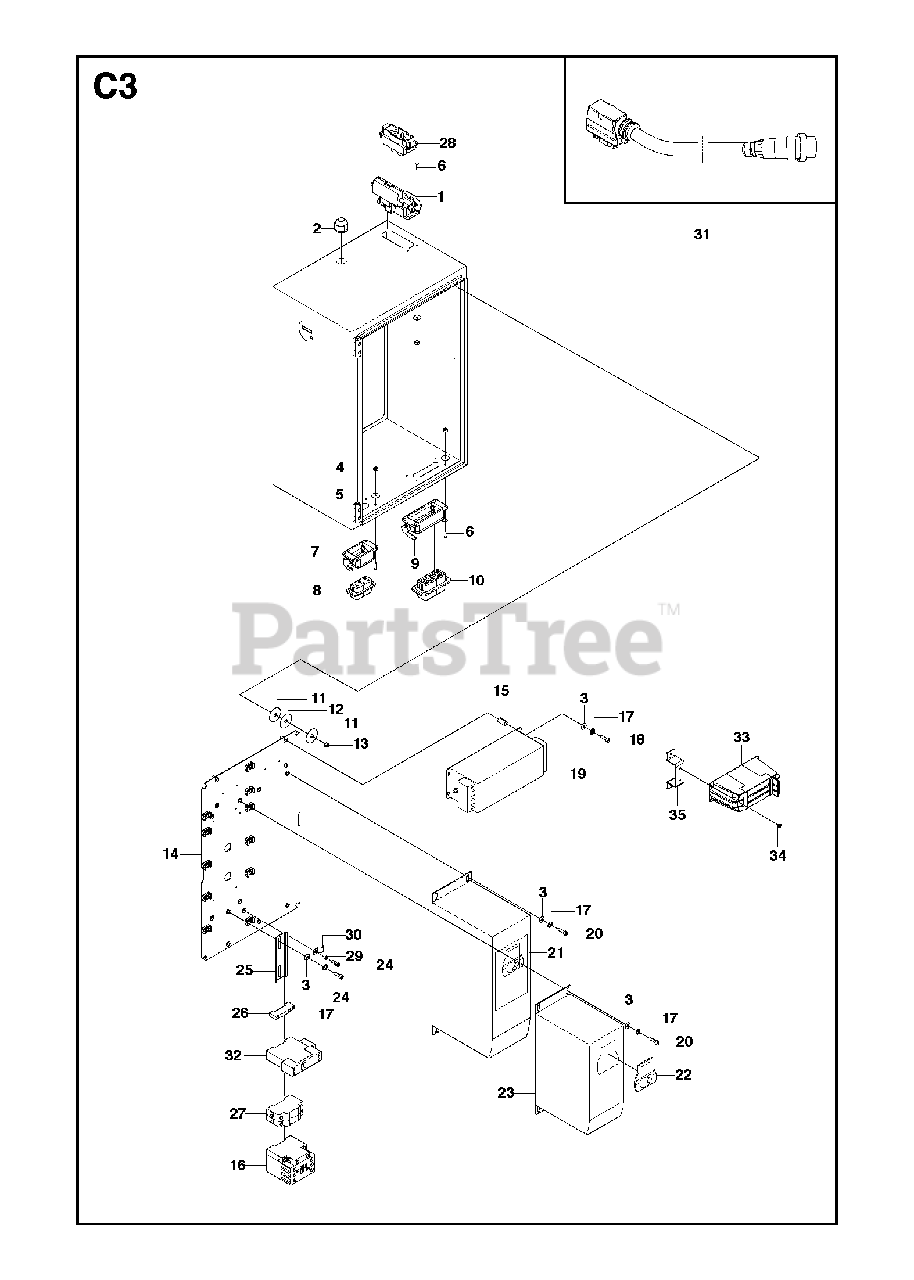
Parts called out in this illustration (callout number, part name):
4	HEXAGON LOCKING NUT
6	SCREW CRPANM
13	HEXAGON LOCKING NUT
17	WASHER10, UL
